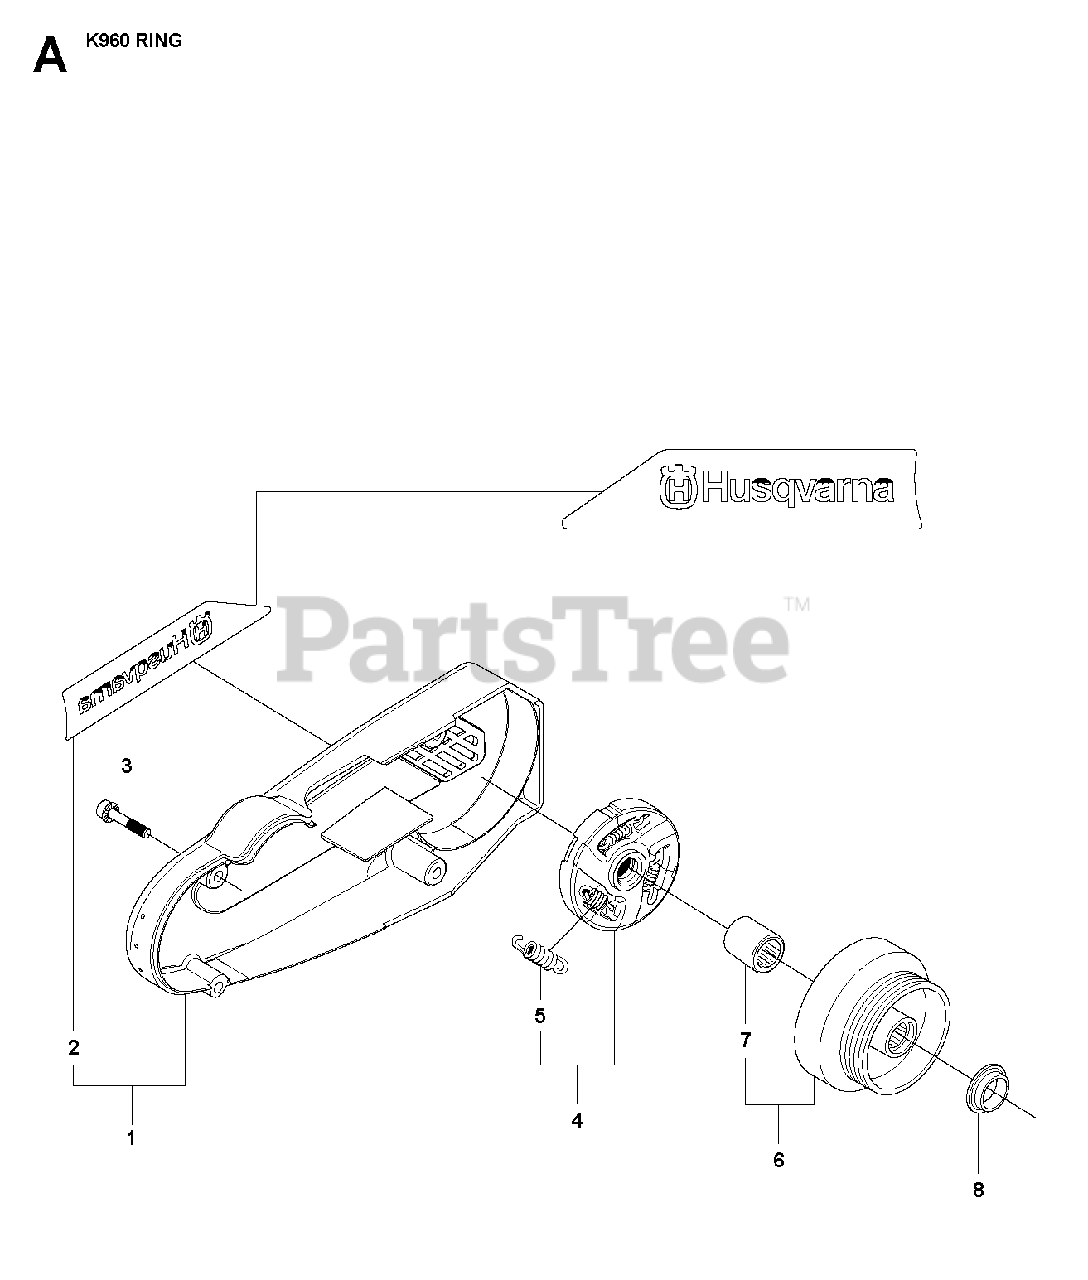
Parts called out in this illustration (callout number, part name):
3	SCREW ITXSCM
4	CLUTCH ASSYIncl. 5
5	CLUTCH SPRING
6	DRIVING PULLEY ASSYIncl. 7
7	NEEDLE BEARING
